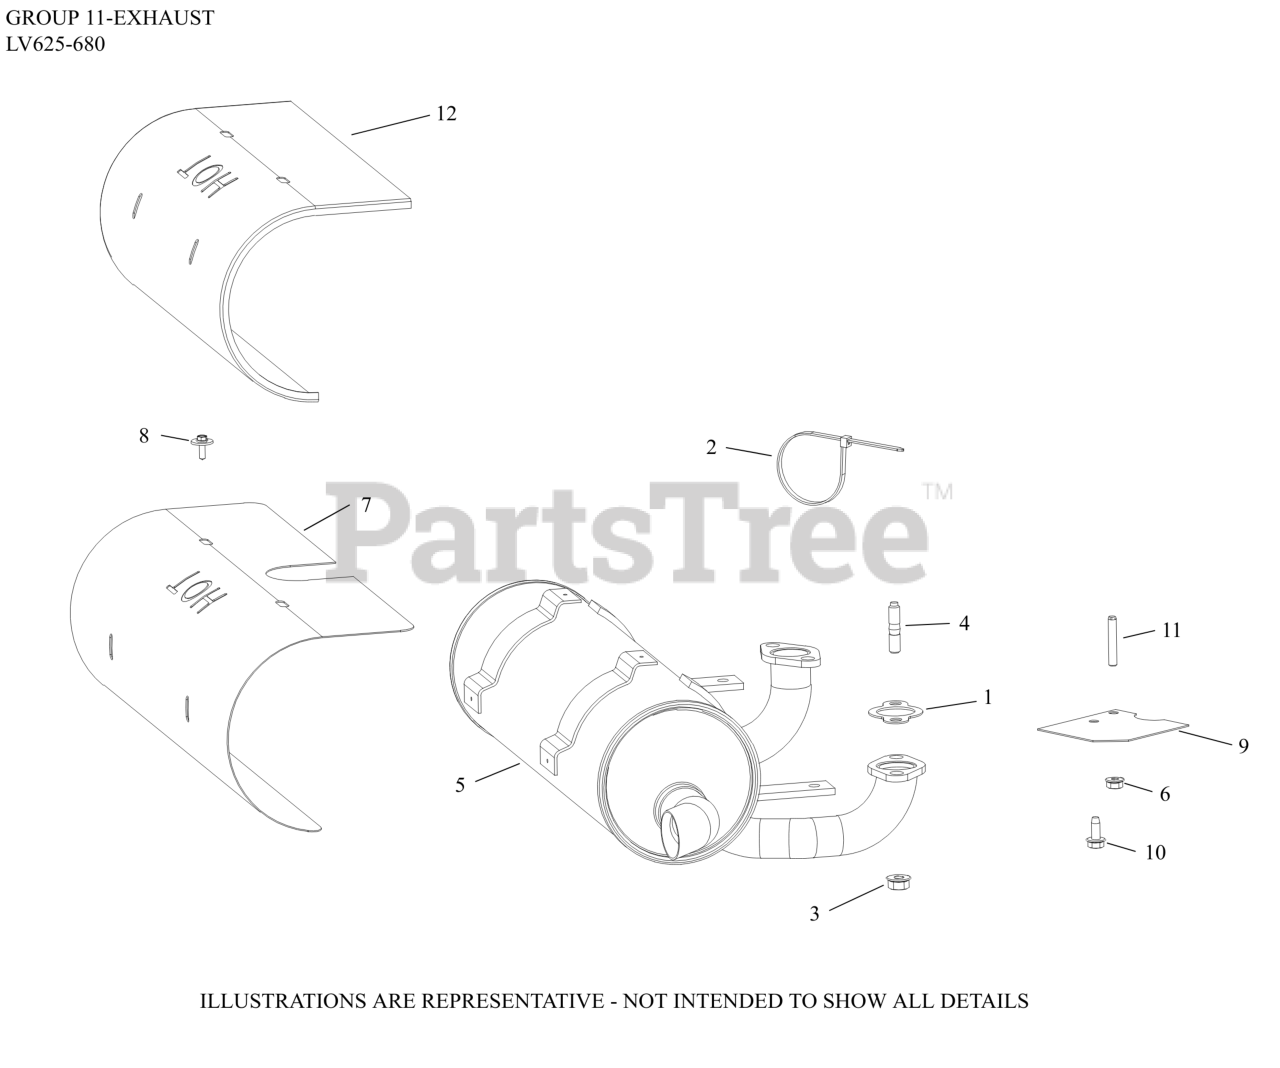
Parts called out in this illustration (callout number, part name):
1	GASKET, EXHAUST
3	NUT, FLG M8X1.25
4	STUD, EXHAUST-USE 25 072 24-S
6	NUT, FLG M6X1.0
7	DUCT, HEAT SHIELD
8	SCREW, SEMS DRILL #8-18X1/2"
9	DEFLECTOR, HEAT
10	SCREW,FLG THD FRM M6X1.0X16-(#25086397S)
11	STUD, M6X1.0X36
